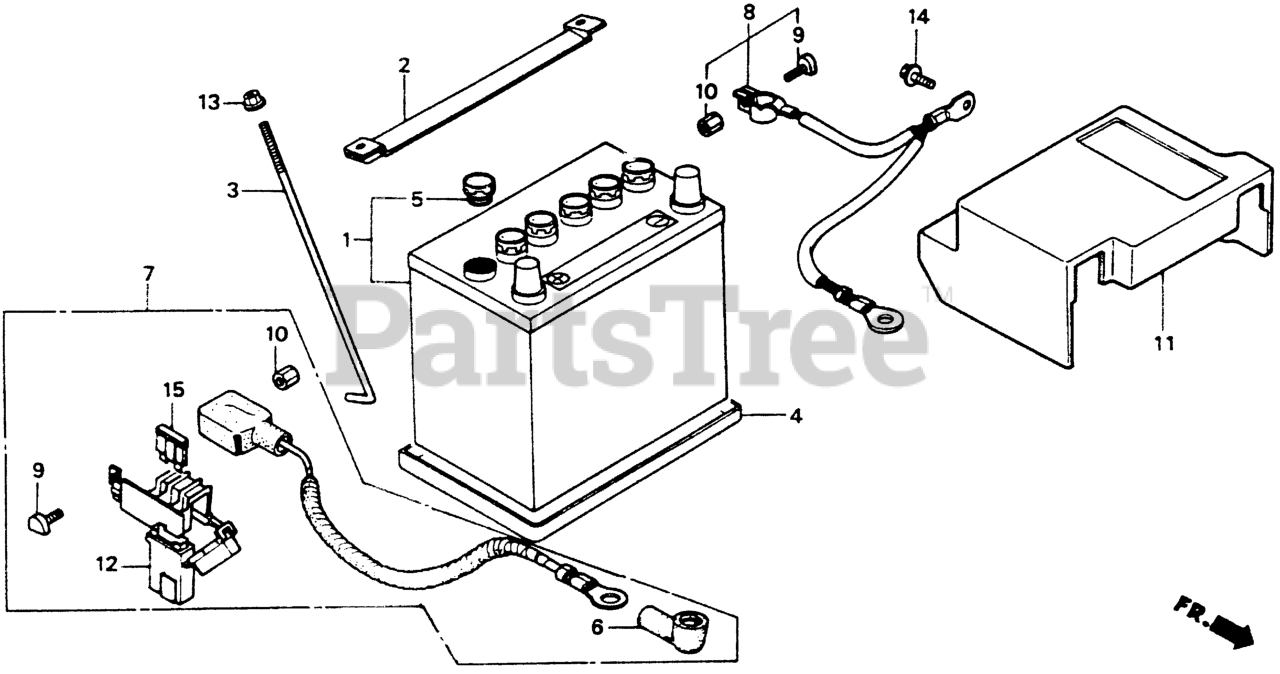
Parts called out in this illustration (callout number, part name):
1	BATTERY ASSY. (32A19RT-S) (YUASA)
1	BTTRY, MF (34A19RT) (S) (MSDS)
1	BATTERY (26A19RT-S) (YUASA)
2	PLATE, BATTERY SETTING
3	BOLT, BATTERY SETTING
4	TRAY, BATTERY
5	PLUG, VENT (YUASA)
6	COVER, TERMINAL
7	CABLE ASSY., STARTER
8	CABLE ASSY., GROUND (NOT AVAILABLE)
9	BOLT, BATTERY TERMINAL (SUMITOMO)
9	BOLT, BATTERY TERMINAL
10	NUT, BATTERY TERMINAL (SUMITOMO)
12	CASE, MAIN FUSE
13	NUT, FLANGE (6MM)
14	BOLT, FLANGE (6X12) Use from Engine SN 2086984.
15	FUSE, BLADE (5A)
